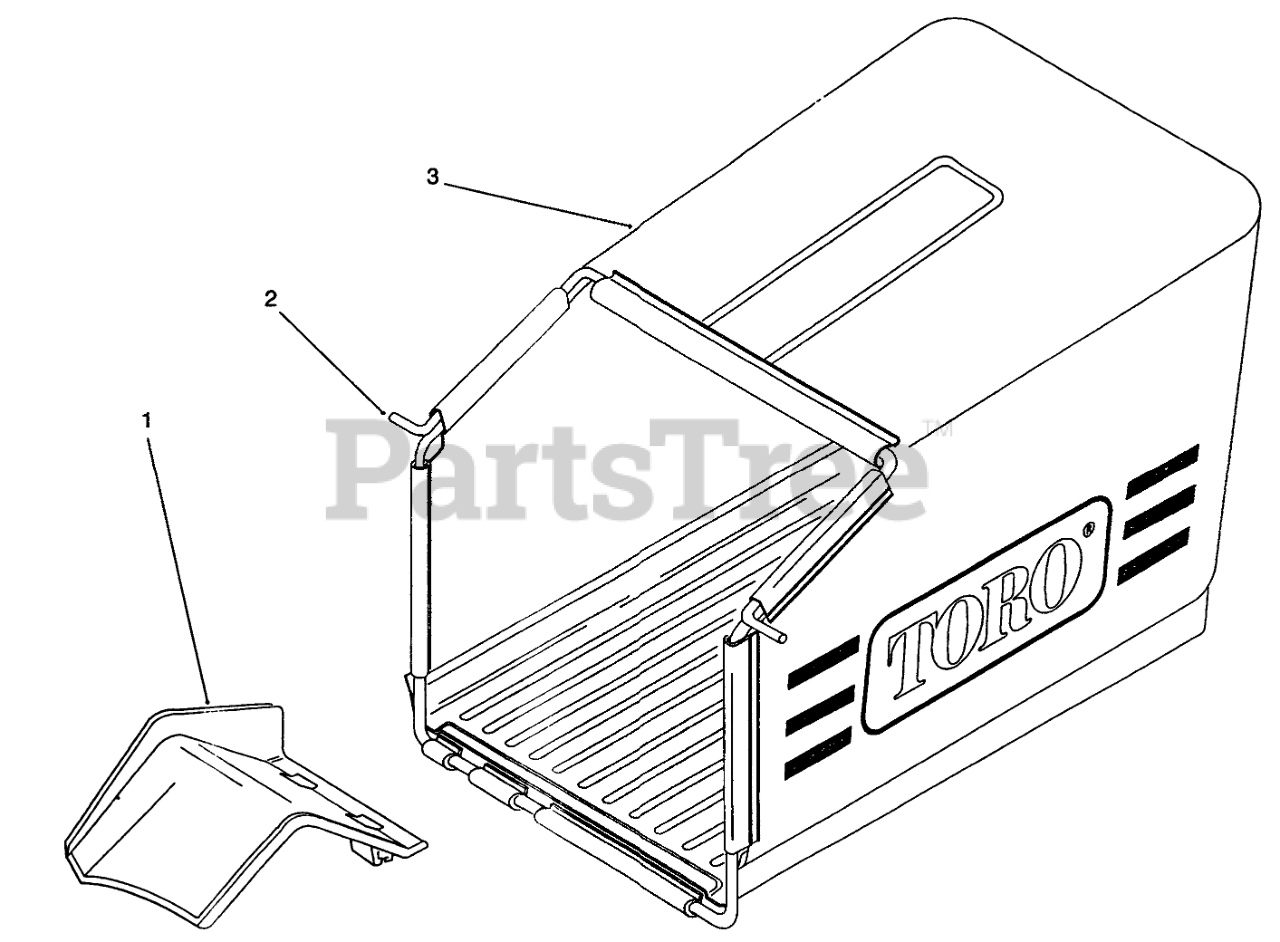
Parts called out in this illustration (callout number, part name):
1	REMOVER-BAG, GRASS
2	FRAME-BAG
3	BAG-GRASS
